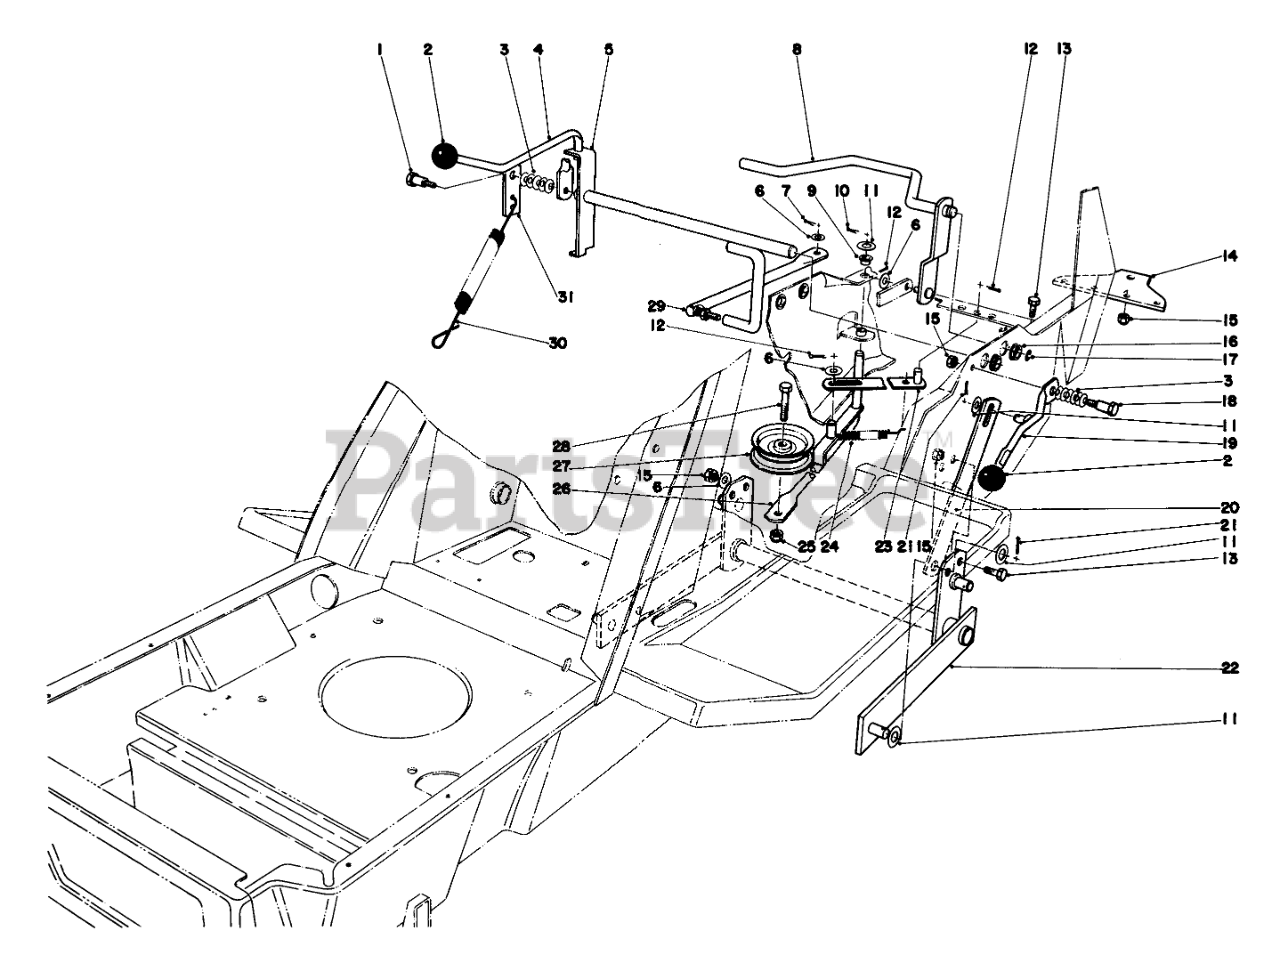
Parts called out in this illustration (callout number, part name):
1	BOLT-SHOULDER
3	WASHER-BELLEVILLE
4	SHIFT LEVER BO
5	Shim Lever
6	Washer
7	PIN-COTTER
8	CLUTCH ACTUATOR WA B
9	BUSHING-NYLINER
10	PIN-COTTER
11	WASHER-FLAT
12	PIN-COTTER
13	SCREW-HH
14	HITCH PLATE R
15	NUT-LOCK, CONE
16	Nyliner
17	E-RING
18	SHOULDER BOLT
19	Handle-Height of Cut
20	HOC LINK B
21	PIN-COTTER
22	Pivot Bar
23	SPRING RET WA B
24	DECK TENSION SPRNG O
25	NUT-LOCK, CONE
26	IDLER ARM WA BO
27	IDLER PULLEY
28	SCREW-HH
29	SHIFT ARM BO
30	EXT SPRING O
31	Bracket Counterbalance Spring
